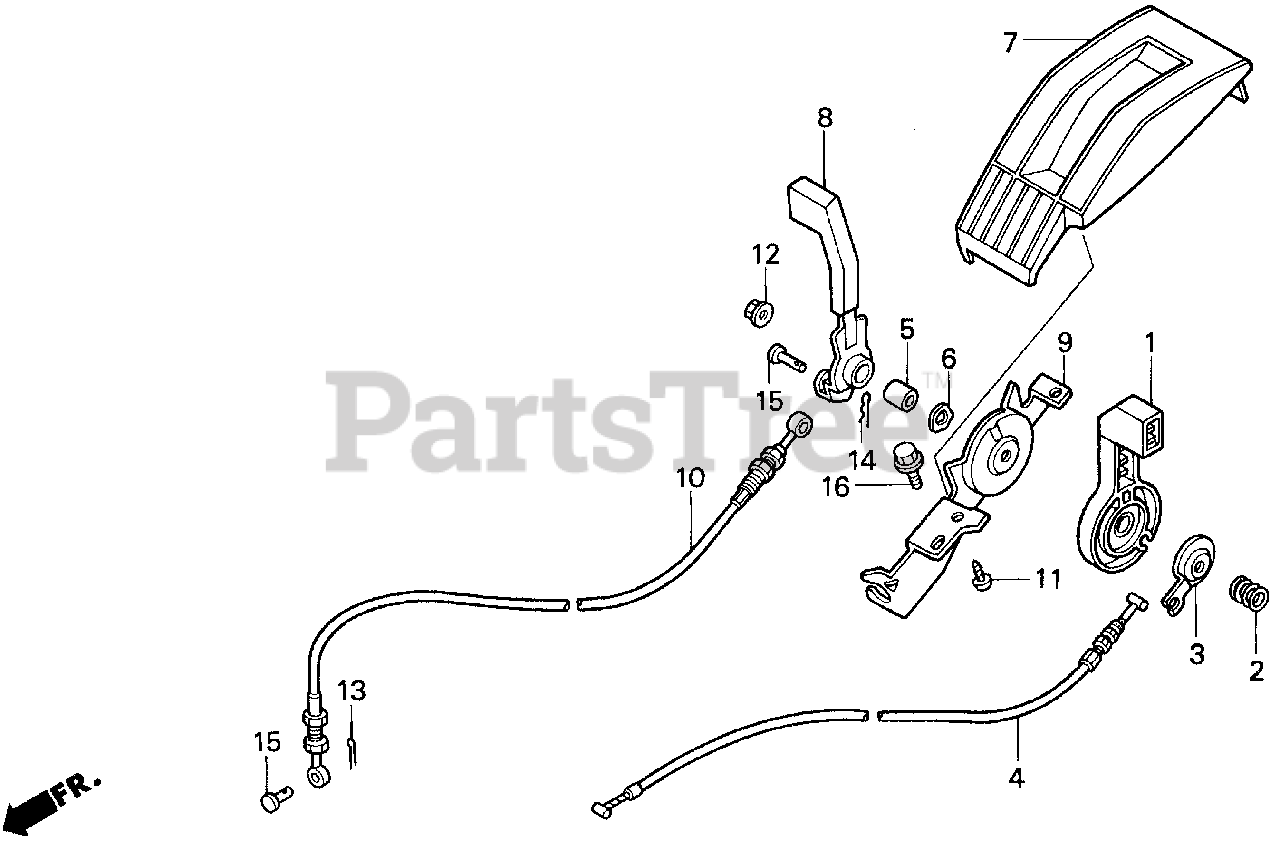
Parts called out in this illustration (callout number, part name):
1	LEVER, THROTTLE
2	SPRING, THROTTLE LEVER
3	SEAT, SPRING
4	CABLE, THROTTLE
5	COLLAR, RECOIL STARTER
6	WASHER, WAVE (11MM)
7	COVER, CONTROL
8	LEVER, CHANGE
9	PLATE, STOPPER
10	CABLE, CHANGE
11	SCREW, TAPPING (5X12)
12	NUT, FLANGE (6MM)
13	PIN, SPLIT (1.6X12)
14	PIN, LOCK (6MM)
15	PIN A, BRAKE ROD JOINT
16	BOLT, FLANGE (6X10)
